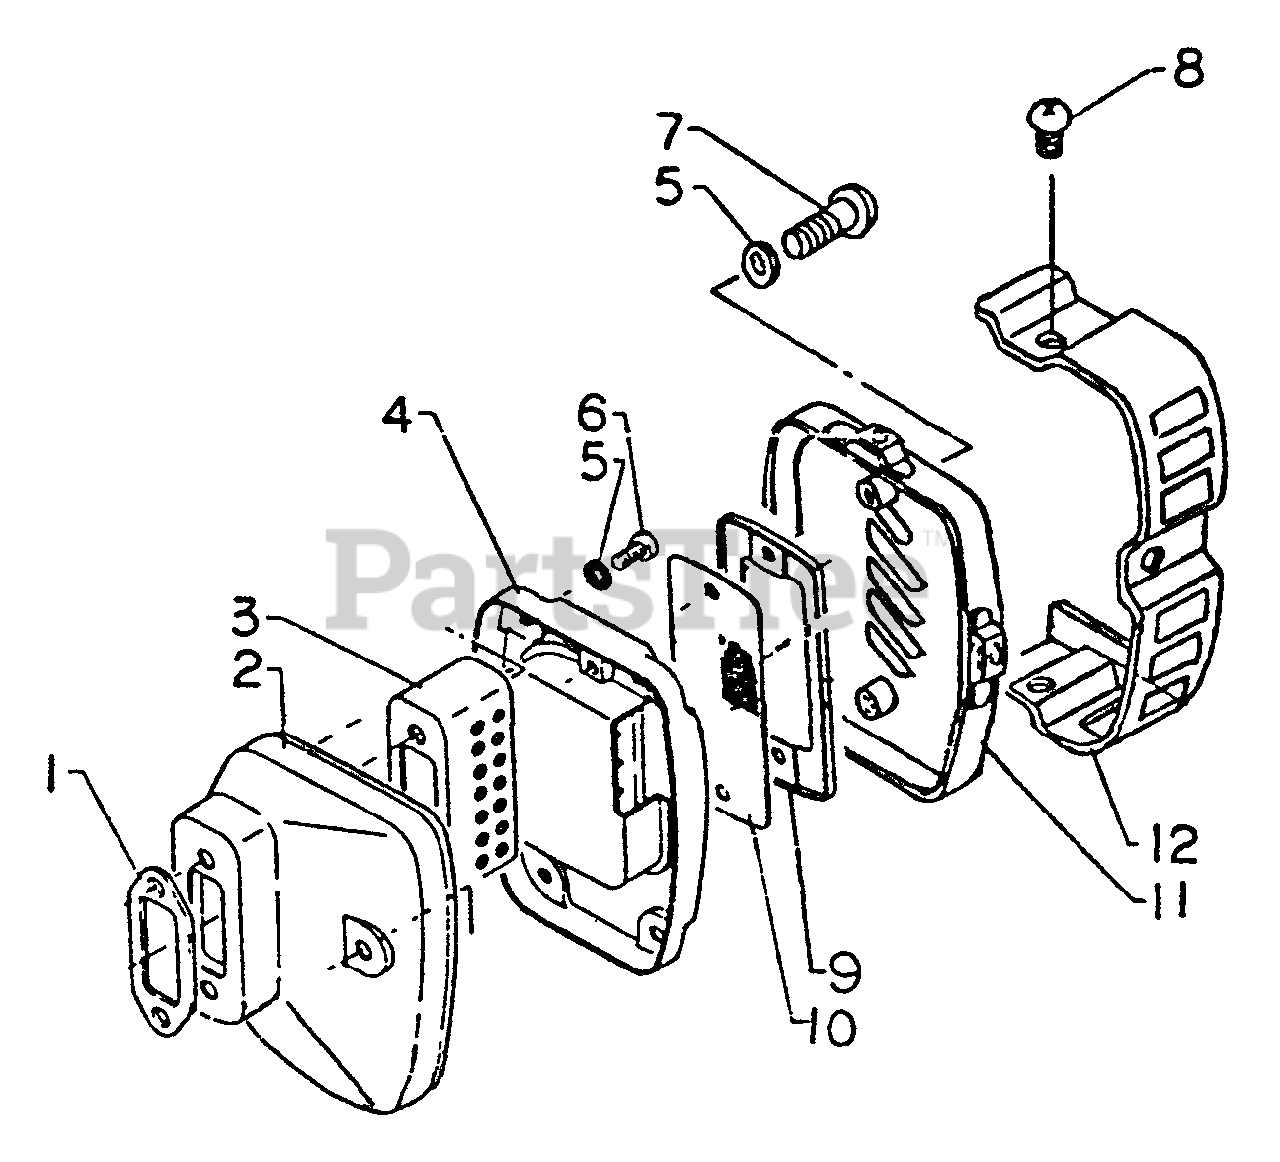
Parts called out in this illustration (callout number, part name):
1	GASKET, EXHAUST
2	MUFFLER
3	BAFFLE, MUFFLER
4	LID, MUFFLER
5	WASHER, LOCK 5 MM
6	SCREW 5×8
7	SCREW - 5×16
8	SCREW 4×6
9	RETAINER, SCREEN
10	SCREEN, SPARK ARRESTER
11	LID, MUFFLER
12	COVER, MUFFLER
